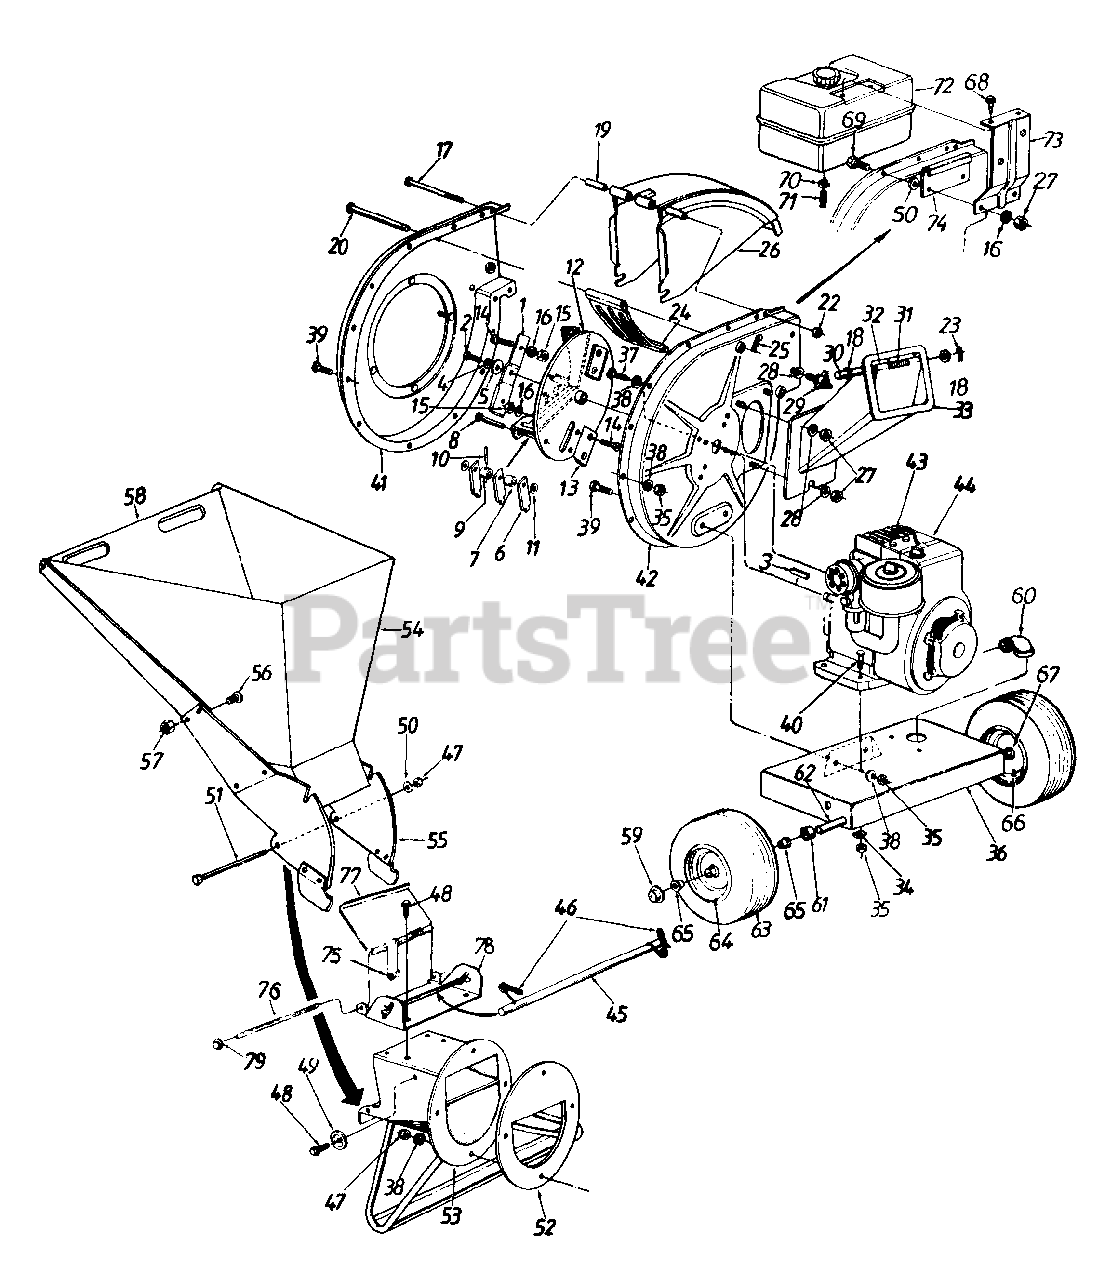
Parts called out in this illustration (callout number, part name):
1	Blade
2	Hex Patch Bolt 3/8-24 x 2" Lg. (Gr. 8)
2	Hex Patch Bolt 3/8-24 x 2.25" (Gr. 8)
3	Sq. Key 1/4 x 2.0" Lg.
4	L-Wash. 3/8" I.D. H.D.
5	Fl-Wash. .406" I.D. x 1.25" O.D. Hdn.
6	Flail
7	Flail Spacer
8	Clevis Pin .496" Dia.
9	Flail Spacer w/.160" Dia. Hole
10	Spring Roll Pin 1.12" Lg.
11	Fl-Wash. .531" I.D. x .94" O.D.
12	Impeller Ass'y. Comp.
13	Chipper Blade
14	Flat Hd. Scr. 5/16-24 x .75" Lg.
15	Hex Top L-Nut 5/16-24 (Gr. 5)
16	L-Wash. 5/16" I.D.
17	Hex Bolt 1/4-20 x 3.75" Lg.
18	Fl-Wash. .281" I.D. x .5" O.D.
19	Chute Hinge Spacer 1.66" Lg.
20	Clevis Pin .5" Dia. x 4.62" Lg.
22	Hex Ctr. L-Nut 1/4-20 Thd.
23	Cotter Pin 3/32" x 5/8"
24	Shredder Screen
25	Internal Cotter Pin 3/8" Dia.
27	Hex Nut 5/16-18 Thd. (Gr. 5)
28	Bell-Wash. .345" I.D. x .88"
29	Hand Knob
30	Chipper Door Rod
31	Torsion Spring 1.14" Lg.
35	Hex Nut 5/16-18 Thd. (Gr. 5)
38	L-Wash. 5/16" I.D.
39	Hex Bolt 5/16-18 x .75" Lg. (Gr. 5)
40	Hex Bolt 5/16-18 x 1.75" Lg.
44	Engine
45	Release Bar
46	Torsion Spring 1.06" Lg.
47	Elastic Lock Nut 5/16-18 Thd.
48	Hex Wash. Hd. Self-Tap Scr. 5/16-18 x .75" Lg.
49	Stop Washer
50	Fl-Wash. 5/16" I.D.
51	Hex Bolt 5/16-18 x 8.38" Lg.
57	Hex L-Nut 1/4-20 Thd.
60	Drain Elbow (5 HP B&S)
60	Drain Elbow (8 HP B&S)
61	Spacer .64" I.D. x .38" Lg.
62	Shredder Axle
63	Wheel Ass'y. Comp.
63	Tire Only
64	Rim Only
65	Flange Bearing .632" I.D.
66	Air Valve
67	Grease Fitting
68	Hex Hi-Low Scr. 1/4 x .75" (650C)
69	Hex Bolt 5/16-18 x .88" Lg. (650C)
70	Hose Clamp (650C)
71	Fuel Line - 7 in.(650C)
72	Fuel Tank Ass'y. Comp.(650C)
75	Torsion Spring
76	Hopper Door Rod
